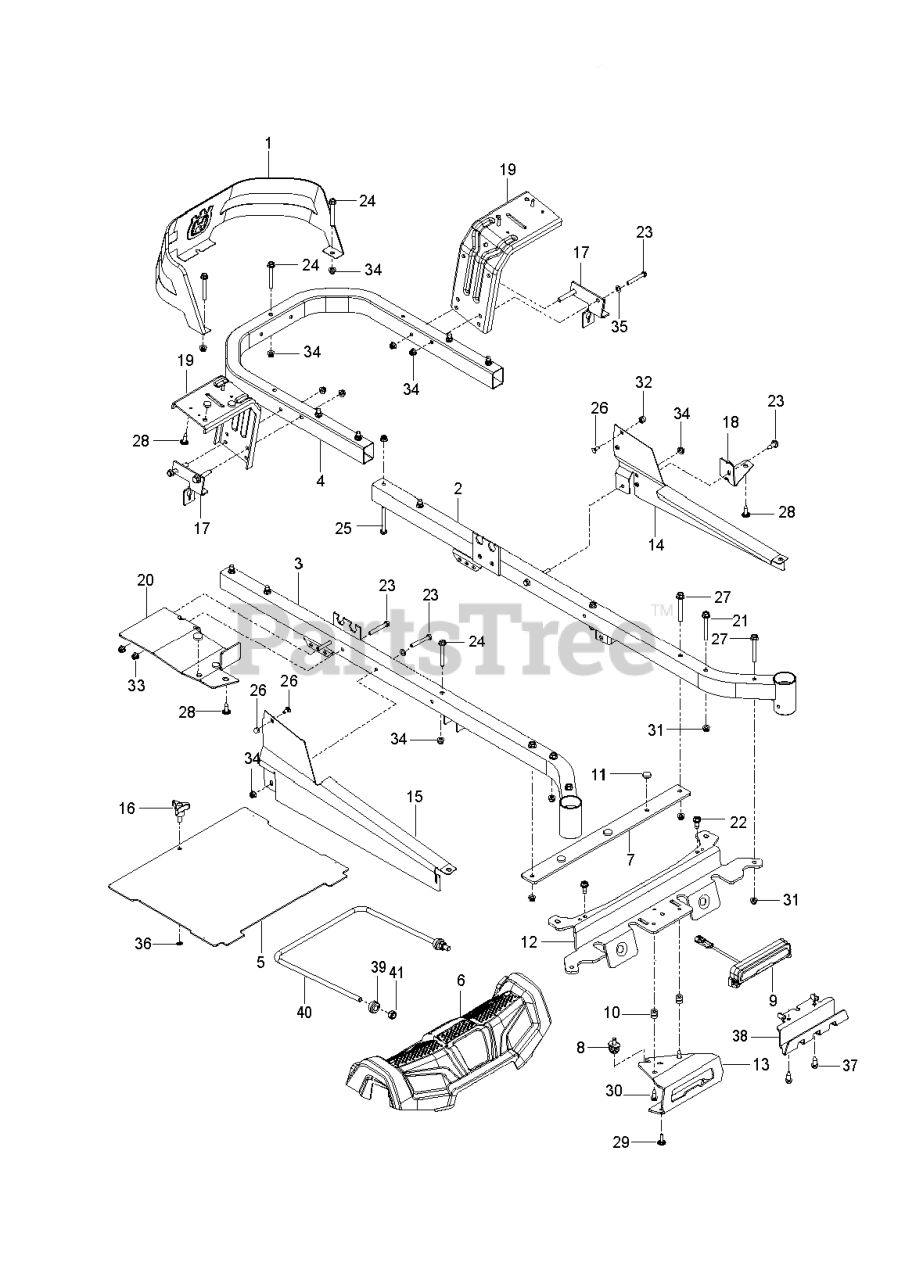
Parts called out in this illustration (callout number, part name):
1	GUARD.ENGINE.HUSQ.RZ.X498
2	FRAME.TUBE.RZ.MAIN.WELD.LH.ORG
3	FRAME.TUBE.RZ.MAIN.WELD.RH.ORG
4	TUBE.PNT.FRAME.RER.HUSQ.23".RZ
5	PLATE RZ FOOTREST HUSQVARNA OR
5	PLATE, FOOT W/DECALS RZ
6	COVER.FOOTREST.REFRESH.ASM
7	FOOTREST.PLATE.SUPPORT.X431
7	SUPPORT.RZ.FOOTREST.PLATE.X43
8	SCREW.ADJ.ISOLATOR.BOLT.ASSY
9	LIGHT.ZTR.LED.ASM
10	GROMMET.RUBBER.PUSHIN
11	GROMMET.BUMPER
12	CROSS.PNT.MEMBER.BLK
13	BRACKET.SKIDPLTE.LED.RFRSHX417
14	COVER.RAIL.RH.RZ.X668
15	COVER.RAIL.LH.RZ.X668
16	KNOB W/STUD
17	BRKT ROD.BYPASS.EZT.X431
18	SUPPORT.PNT.RH.CONSOLE.FRONT
18	SUPPORT RZ REFERSH LH CONSOLE
19	FENDER.SUPPORT.PNT.X431
20	SUPPORT RZ REFRESH RH CONSOLE
20	SUPPORT.PNT.RH.CONSOLE.FRONT
21	BOLT SHOULDER,FLANGED,3/8-16X3
21	Bolts
22	BOLT.5/16-18.THRD.ROLL.SHOULDR
23	BOLT.FIN HEX 5/16-18UNC X2 1/4
25	BOLT.HEX.FIN.3/8-16 X 3.GR5
25	Bolts
26	BOLT.CARRIAGE.5/16-18.7/16
26	NUT ACORN,FLANGED,5/16-18
27	HHFS 3/8-16 X 3 GRD 5 ZD
28	SCREW.#10 X 0.750.BOS
28	Screws
29	SCREW.#10 X 0.500
30	BOLT.5/16-18X1.25
31	GSPW Nuts
31	NUT 3/8-16 HEX FLG NYLOC ZD
32	NUT ACORN,FLANGED,5/16-18
33	NUT LOCK HEX FLANGE 5/16-18
33	GSPW Nuts
34	NUT HEXAGON FLANGE 5/16-18 ST
34	5/16-18 NYLOC FLANGE NUT
35	WASHER
36	WASHER 5/16"
37	BOLT.5/16HEX.WHS.HD
38	SKID.PLATE.PNT.RZ.REF.SIVER
39	BUSHING SPHERICAL SUSP. FRONT
39	Bushings
40	Links
40	LINK, FRONT SUSP.
41	Nuts
